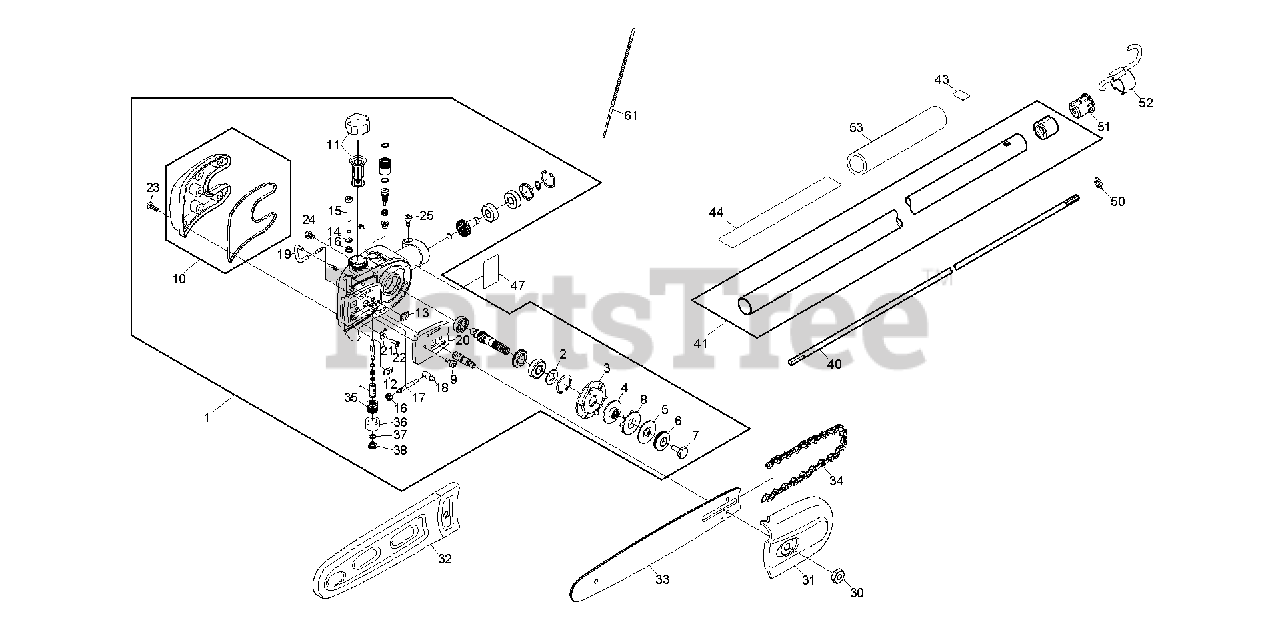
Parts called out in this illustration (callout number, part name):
6	SPRING, DISK
7	SCREW, LOCKING (M6)
9	BOLT, TORX (5X12)
12	PADDING BLOCK, R.
13	PADDING BLOCK, L.
14	E-RING (E-5)
15	BOLT, ADJUSTING
16	GEAR, ADJUSTING
17	SCREW, ADJUSTING
18	PIN, ADJUSTING
21	BLOCK, SUPPORT
22	SCREW, FLAT-HEAD (4X10)
23	BOLT, BOTTON (5X14)
24	BOLT, BOTTON (6X8)
25	BOLT, TORX (6X20)
31	COVER, COLOPHONY
32	COVER, CUTTER
35	FILTER, PUMP
36	FILTER, SPONGE
40	SHAFT, DRIVE
43	MARK, ARROW
44	MARK, CAUTION
47	MARK, EMBLEM (SSPP)
